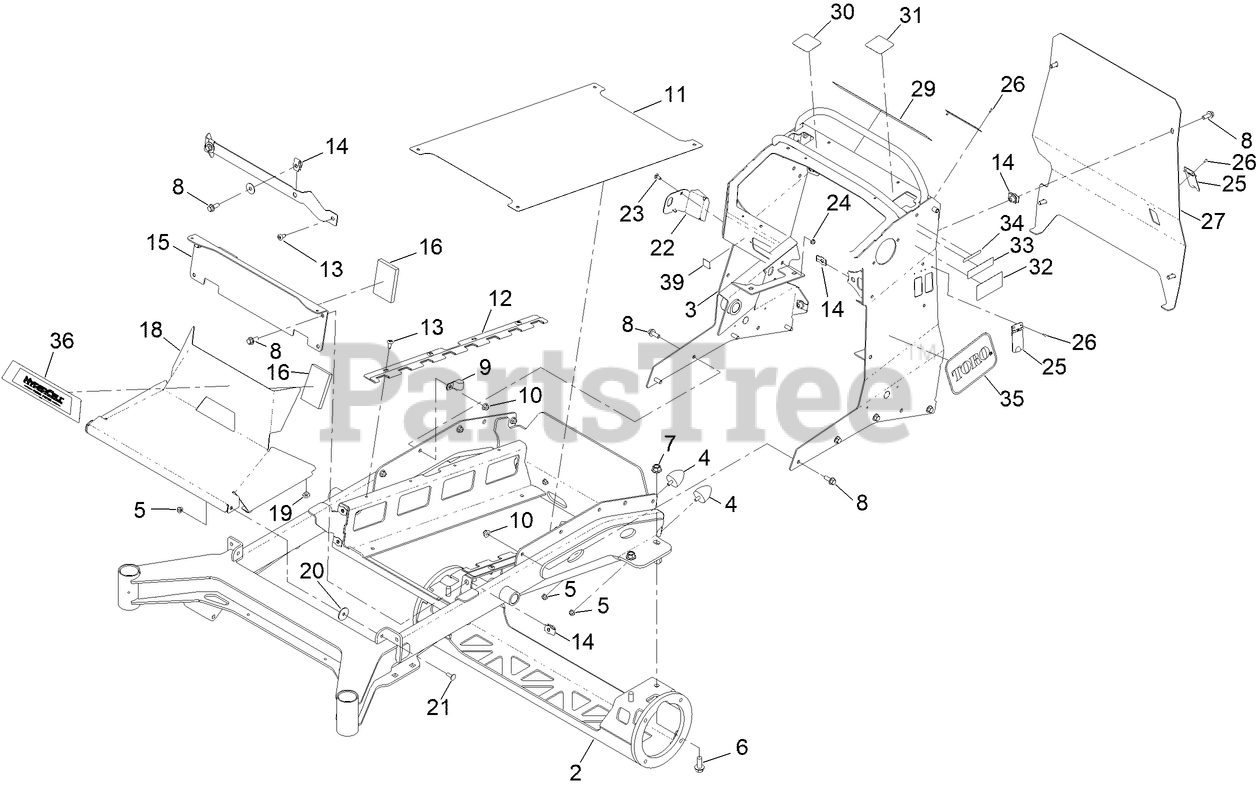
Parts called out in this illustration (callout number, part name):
2	FRAME-AXLE ASM [RED]
3	TOWER ASM
4	BUMPER-RUBBER
5	NUT-HF, NI
6	SCREW-HHF
7	NUT-LOCK
8	SCREW-HHF
9	CLAMP-R
10	NUT-HF, NI
11	PLATE-SKID
12	BRACKET-RETENTION, BATTERY
14	NUT-TINNERMAN
15	PLATE-BATTERY MNT
16	PAD-FOAM
18	COVER-MOTOR CONTROLLER
19	BUMPER
20	WASHER-NYLON
21	BOLT-CARR
22	PLATE-LATCH
23	SCREW-CARR
24	NUT-HF
25	PLATE-COVER, SPRING
26	RIVET-POP
27	PLATE-COVER, PLATE
29	DECAL-WARNING
30	DECAL-OPC CONTROL, RIGHT
31	DECAL-OPC CONTROL, LEFT
32	DECAL-CHARGING PORT
33	DECAL-SERVICE, SHUT-OFF
34	DECAL-WARNING
35	DECAL-TORO LOGO
36	DECAL-HYPERCELL 1900
39	DECAL-LIGHT, WARNING
